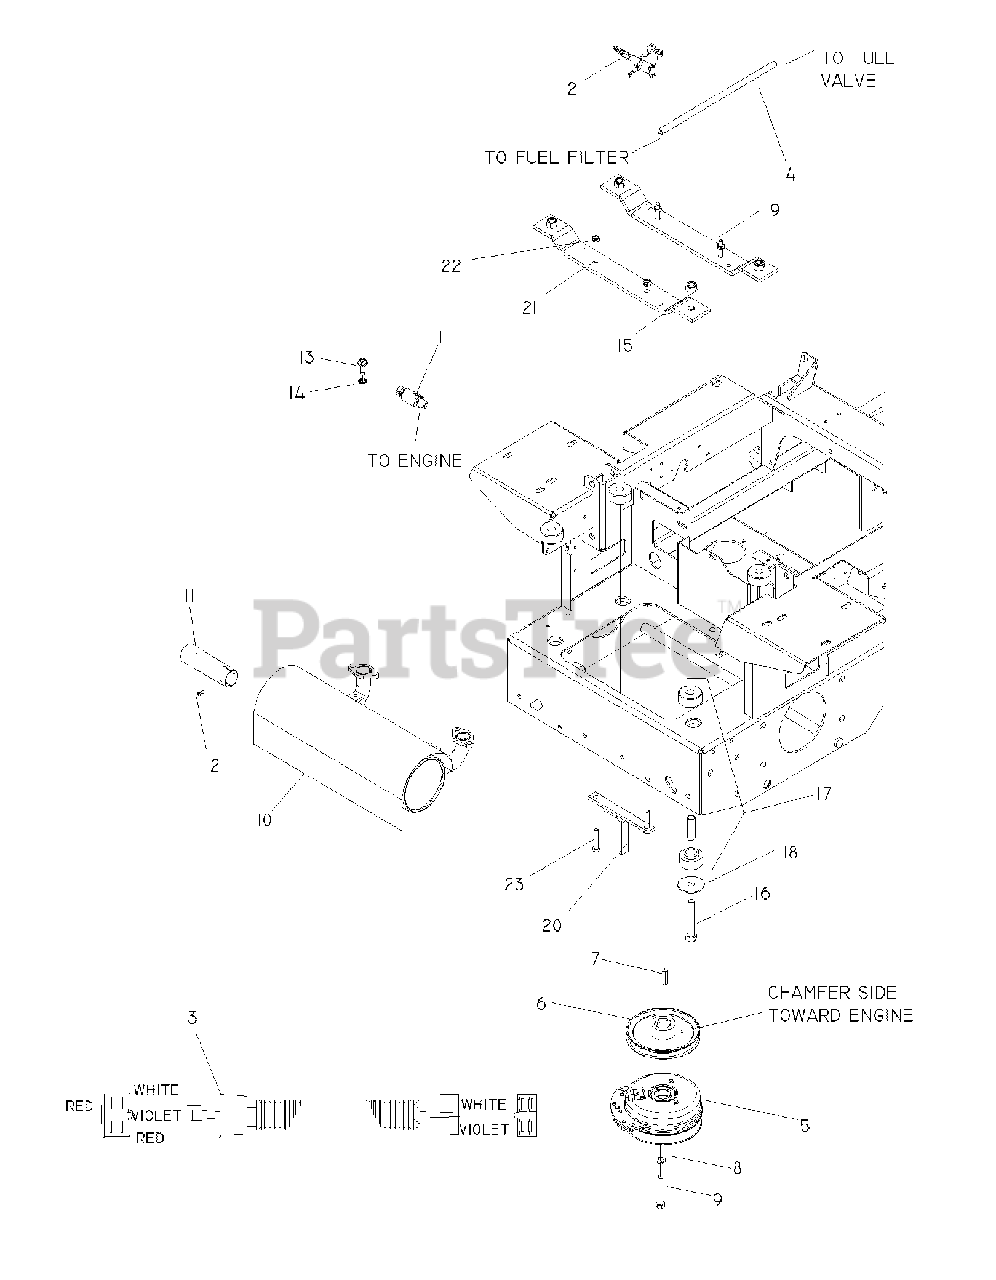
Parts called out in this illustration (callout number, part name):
1	OIL DRAIN FITTING
2	CHOKE CABLE
3	KOH PIGTAIL
4	FUEL LINE 13"
5	ELECTRIC CLUTCH W/CABLE
7	KEY, 1/4 SQ X 1 1/4
8	WASHER 7/16 LOCK
9	BOLT 7/16F X 2 1/2
10	MUFFLER
11	TUBE, EXTENSION, MUFFLER
12	SCR #8 X 1/2 PHIL HD DRILL BLK
13	BOLT 3/8-16 X 1.0
14	WASHER 3/8 EXT STAR ZD
15	NUT 1/2-13 HEX NYLOC ZD
16	HCS 1/2C X 3 1/4
17	ISOLATORS
18	ISOLATOR WASHER
19	ENGINE MOUNT
20	CLUTCH TIE DOWN
21	STRAP, ISO, REAR
22	NUT 5/16C CENTERLOCK
23	HCS 5/16-18 X 1-3/4 SERATED
